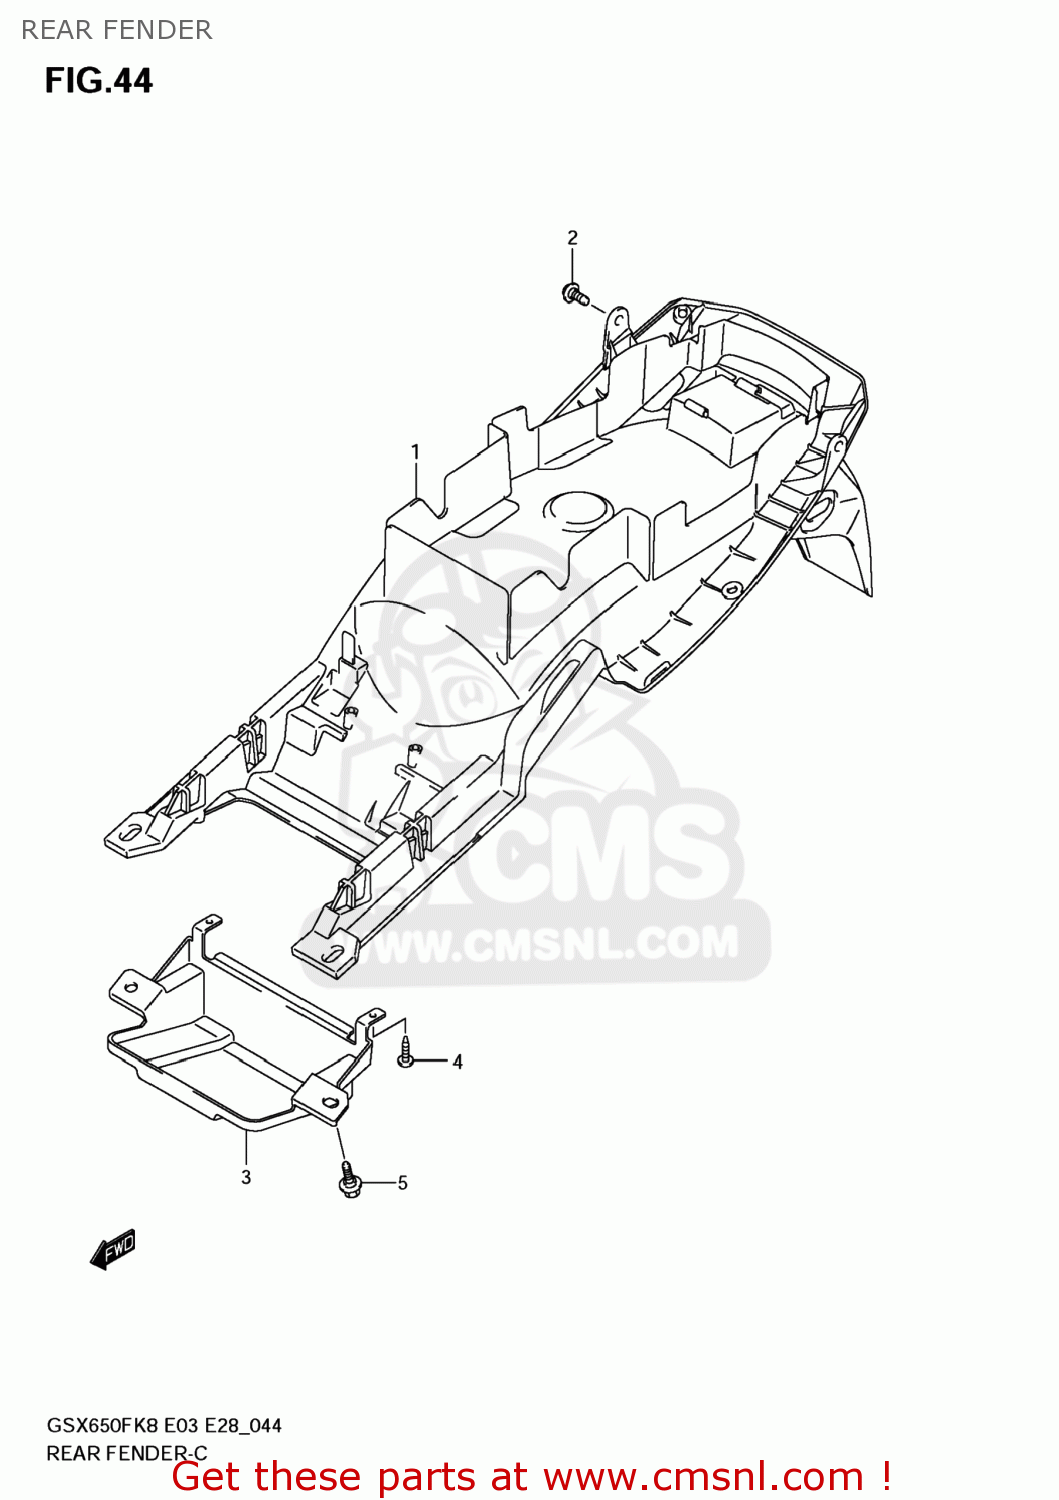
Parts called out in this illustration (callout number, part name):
1	FENDER,RR
2	BOLT
3	COVER
4	SCREW
5	BOLT(6X17.8)
